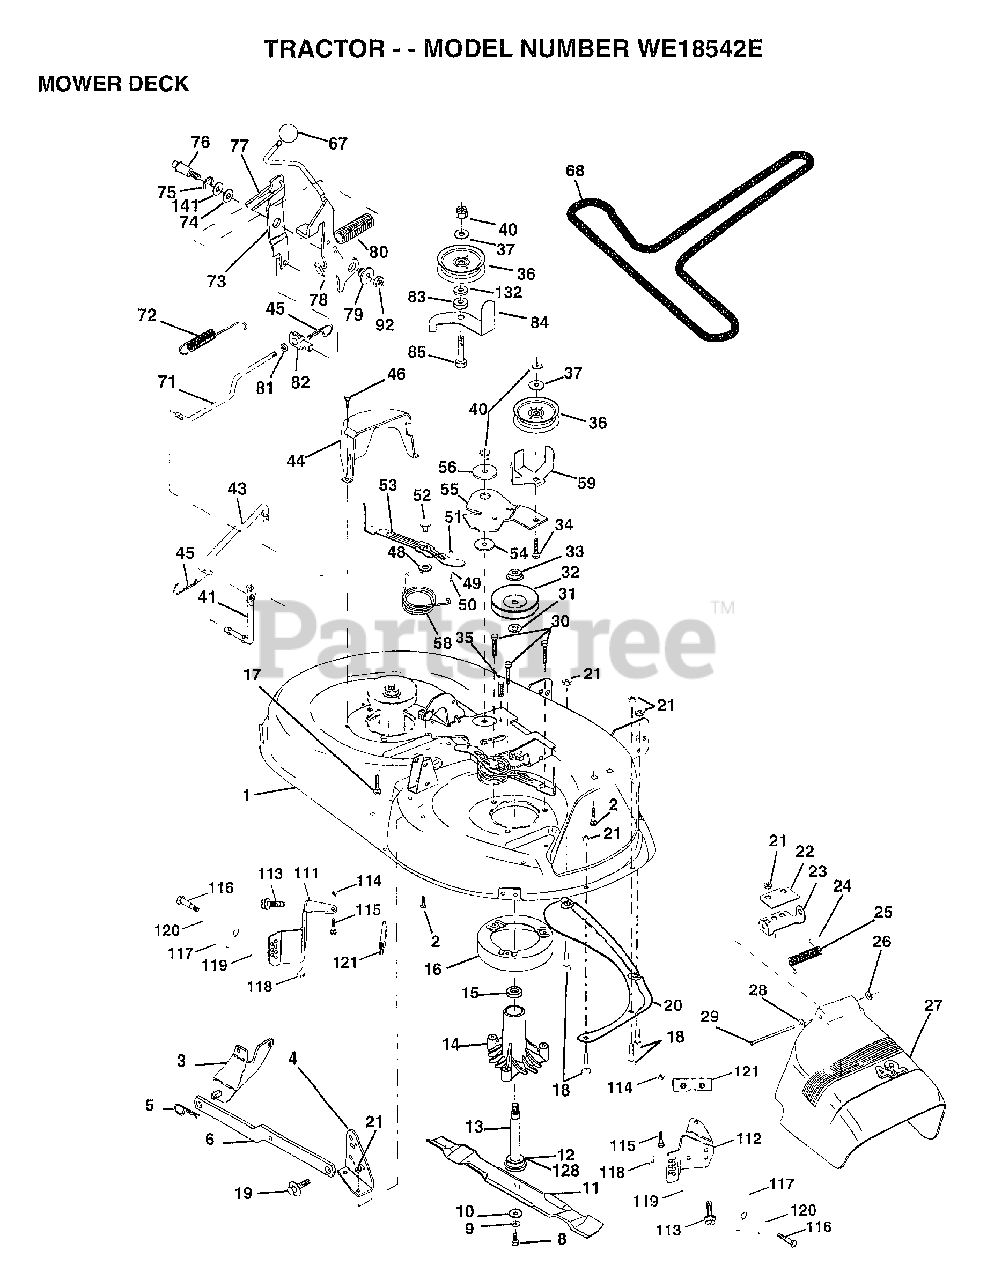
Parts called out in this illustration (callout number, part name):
1	"HOUSING ASSY.42"""
2	BOLT
3	BRKT ASM SWAY BAR
4	BRKT DECK SW BAR
8	BLADE BOLT
10	WASHER.HARD.BLADE
11	"BLADE.42"" HIPERF"
12	BEARING.BALL
14	HSG ASM MANDREL
15	BEARING
16	STRIPPER RND MWR
17	BOLT RDHD 3/8-16
18	BOLT
19	BOLT SHD 5/16-18
20	BAFFLE VORTEX 42
22	STIFFENER BRKT
23	DEFLECTOR BRKT
24	CAP-SLEEVE LT
25	SPRING TORSION
26	NUT PUSH M
27	DEFLECTOR.SHIELD
28	WASHER
29	HINGE ROD
30	"SCREW-THD ROLL,WA"
31	WASHER
32	PULLEY.MANDREL.42
34	BOLT
35	XMAS TREE FASTNER
36	FLAT IDLER PULLEY
37	WASHER
41	PIVOT ROD
43	ROD CLUTCH W/NIBS
44	GUARD MAND LH BLK
45	RETAINER M
46	SCREW.1/4-20X5/8
48	HARD SMALL WASHER
49	ROLLER ASM-CAM
50	SHOULDER BOLT
51	LOCKNUT
52	BOLT.SHLD.5/16-18
53	BRAKE PAD ARM ASM
54	HARDENED WASHER
55	ARM-IDLER
56	SPACER RETAINER
58	SPRING TORSN BRAK
59	GUARD IDLER TUV
67	KNOB.RD.7/16-14
68	BELT.V.T-PATH
71	ROD CLUTCH 38/42
72	RETURN SPRING
73	CLUTCH ARM SECOND
74	WASHER
75	RING
76	SHOULDER BOLT
77	SPRING KEEPER
78	LEVER.ASM.CLUTCH
79	BUSHING
80	SPRING.CLUTCH.MWR
81	NUT
82	TRUNION ADJ
83	WASHER
84	"KEEPER-BELT,FIXED"
85	BOLT
92	NUT
111	BRACKET.GWHL.LH.
112	BRACKET.GWHL.RH.
113	SCREW
116	BOLT M
117	WHEEL.GAGE.BLK.PL
118	LOCKNUT
119	WASHER
120	WASHER
121	BRACKET.EXTRD.GWL
128	WASHER.FELT.
132	WASHER GT
141	WASHER .T
